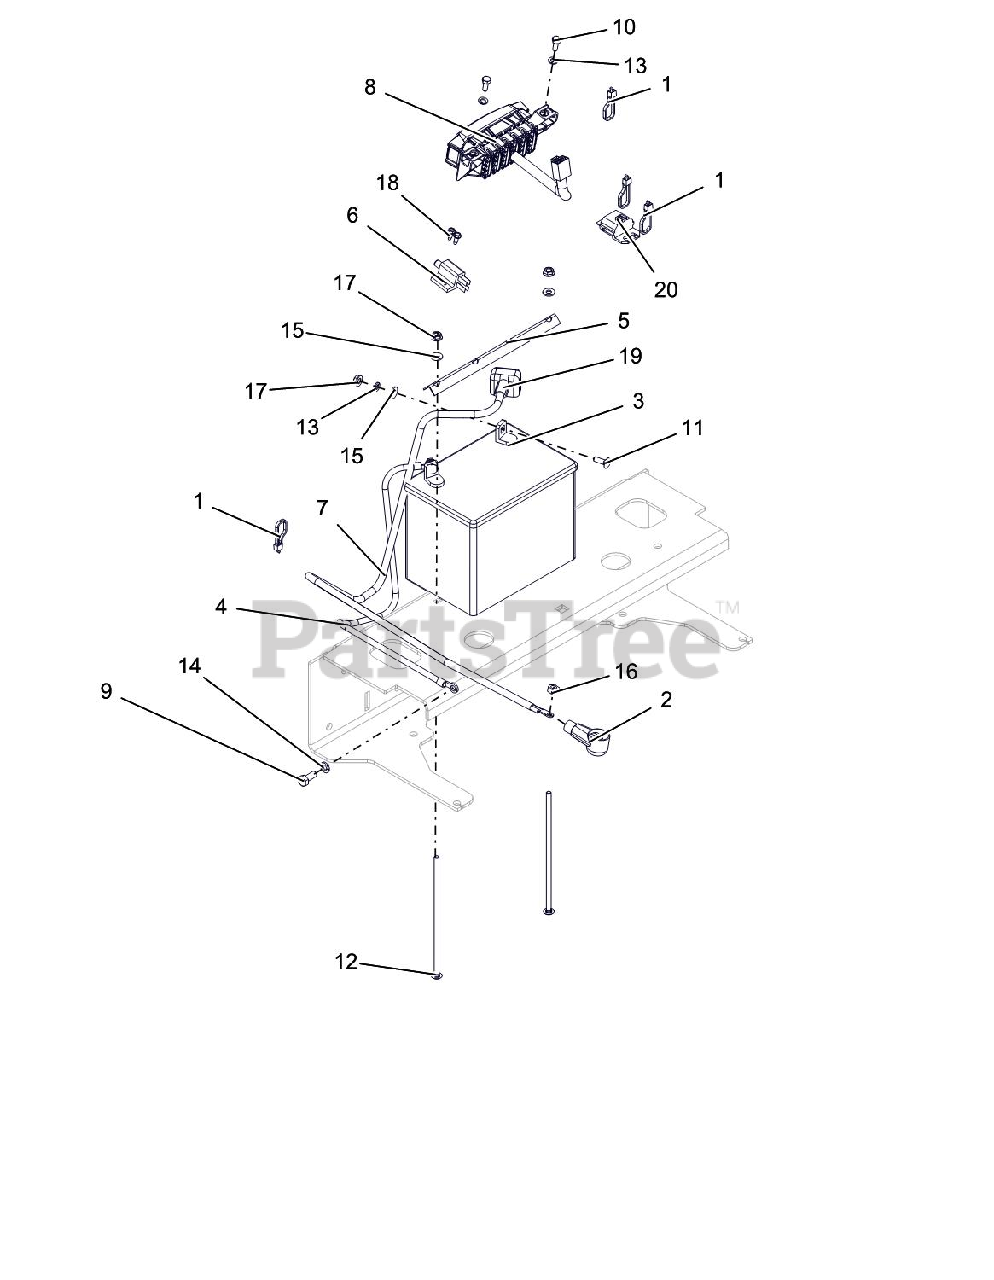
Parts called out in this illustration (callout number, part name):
1	CABLE TIE, .15 X 8.50
2	BOOT, BATTERY TERMINAL-RED
3	BATTERY, 300 CCA 10U1L
4	CABLE-NEGATIVE BATTERY 35.00"
5	HOLD DOWN
6	SWITCH- DOUBLE POLE N.O./N.O.
7	CABLE, BATTERY - 42" POSITIVE
8	HARNESS, PROSTANCE WIRING
8	FUSE,10 AMP MINI-ATC
8	FUSE,15 AMP MINI-ATC
8	FUSE,20 AMP MINI ATC
8	RELAY,MICRO5 TERML W/RESISTOR
8	DIODE, CONNECTOR SHELL
8	FUSE, 20 AMP BLADE S/O
9	@BLT-HEX M8-1.25X20 YWZC
10	@BLT-HEX M6-1X16 YWZC
11	@BLT-RDHDSQNK .25-20X.75 G5YZ
12	BLT-RDHDSQNK .25-20X7.50 GR2YZ
13	@WSHR-LK .25X.062 REG YWZC
14	@WSHR-LK .31X.078 REG YWZC
15	@WSHR-FL-STL.281X.62X.065 YWZC
16	NUT-LK-TOP M8-1.25 YWZC
17	@NUT-SPNLK-FLG .25-20 YWZC
18	@SCR-TAP 10-24X.50 HWH TR YWZC
19	INSULATOR
20	MODULE,INTERLOCK,DELAY, 1801
